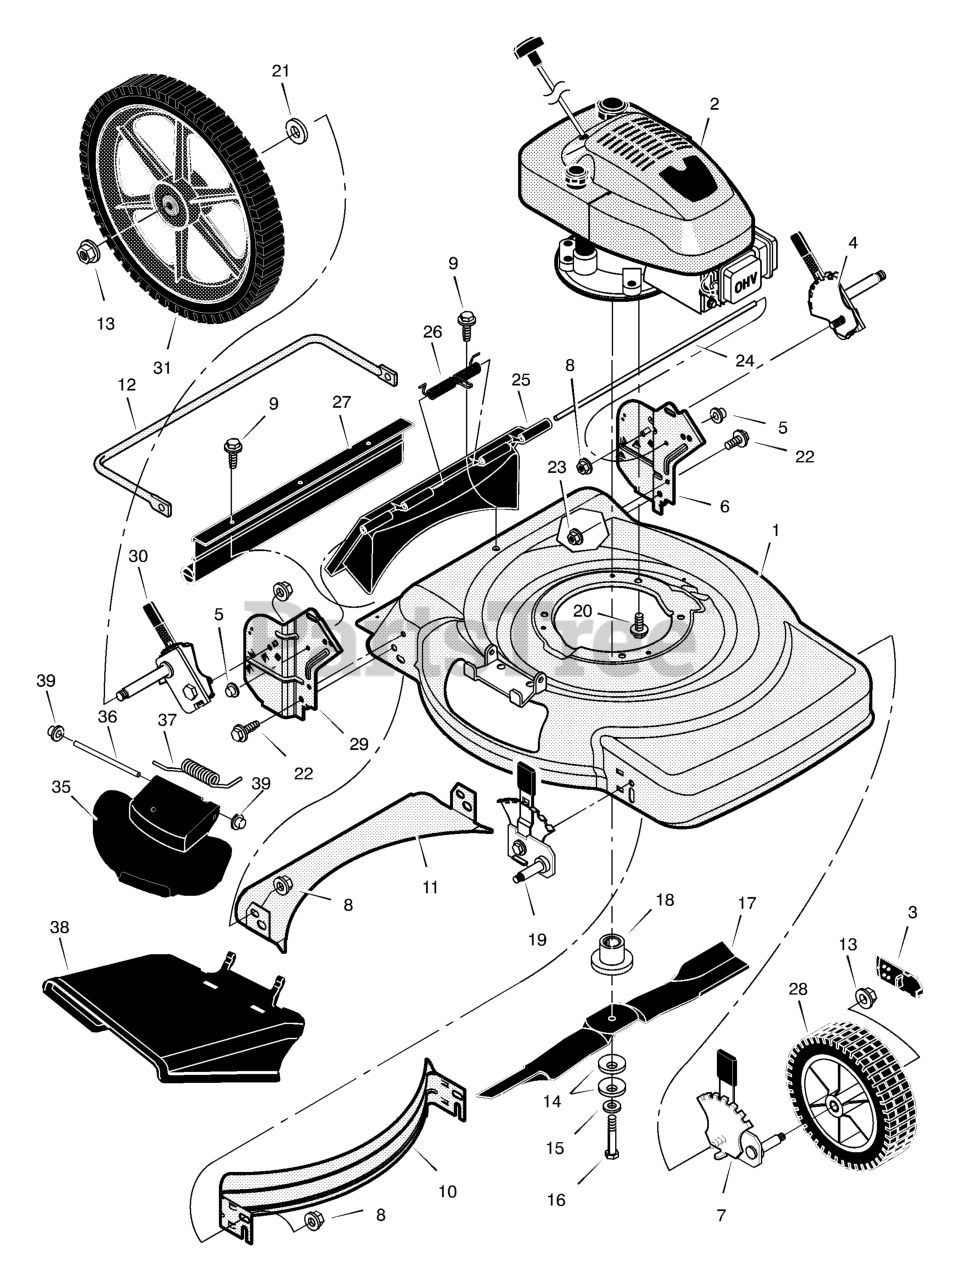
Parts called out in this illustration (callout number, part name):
2	Engine *
3	Cap, Hub
4	Adjuster, Left Rear Height
5	Push On Cap
6	Bracket, Left Handle
7	Adjuster, Left Front Height
8	Nut, Flange
10	Baffle, Front
11	Baffle, Rear
13	Nut, Flange
14	Washer, Belleville
18	Adapter, Blade
19	Adjuster, Right Front Height
20	Bolt, Engine
22	Bolt
23	Nut, Flange
24	Rod, Pivot
25	Door, Rear (Black)
27	Guard, Rear
28	Wheel & Tire, Front
29	Bracket, Right Handle
30	Adjuster, Right Rear Height
31	Wheel & Tire, Rear
35	Cover, Mulch (Black)
36	Rod, Pivot
37	Spring, Torsion
38	Deflector, Chute (Black)
39	Push On Cap
